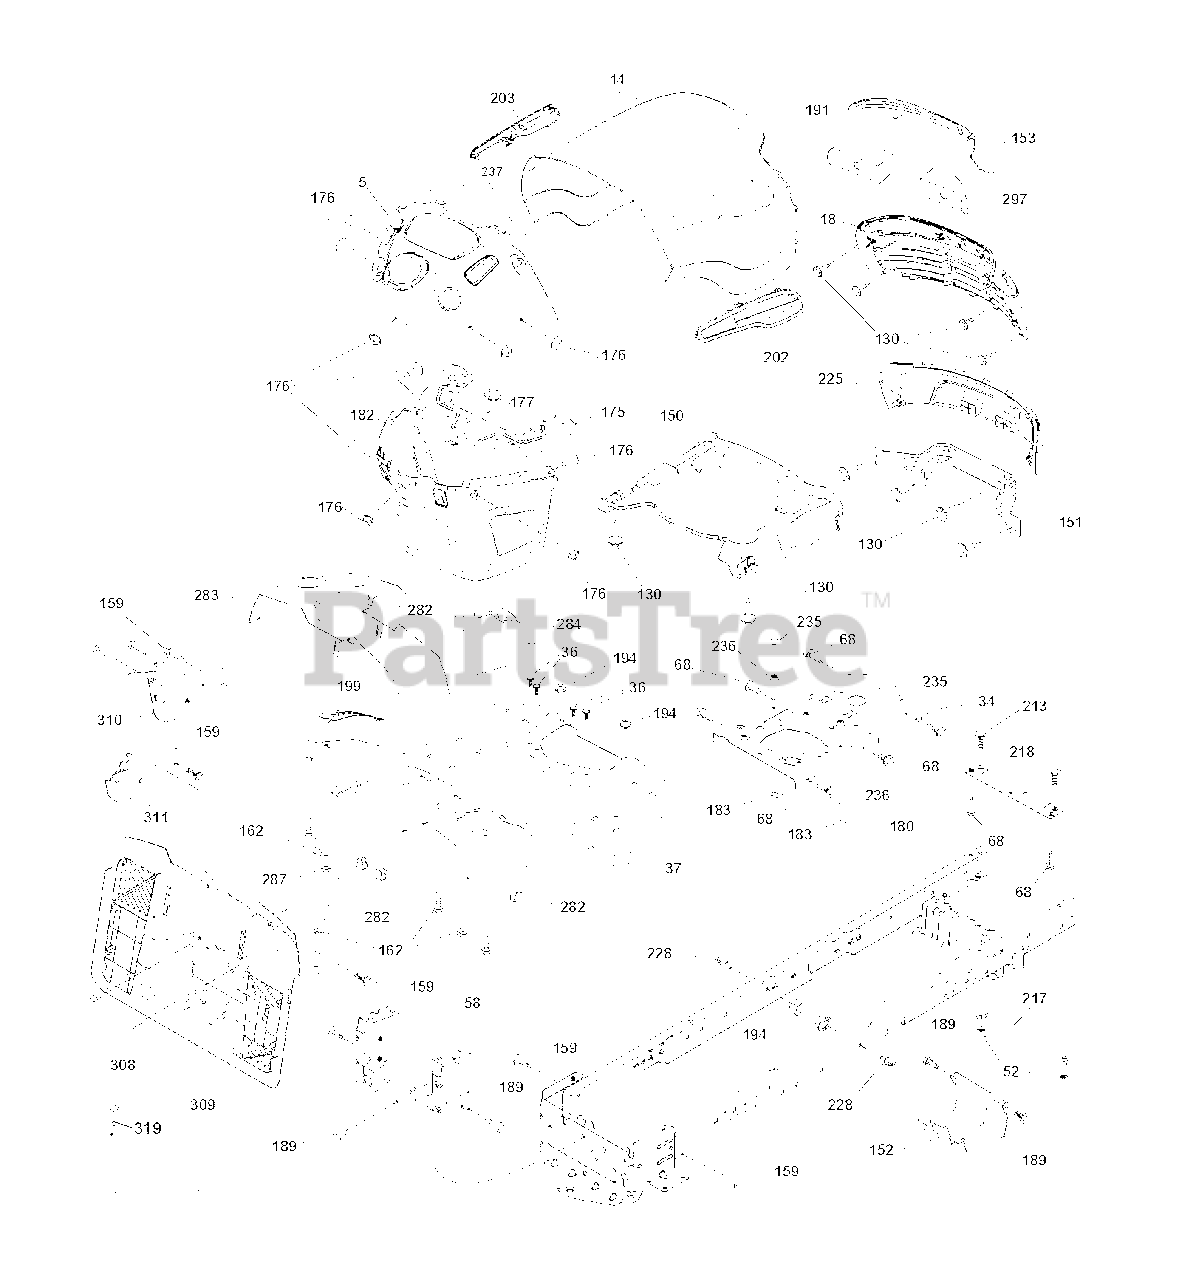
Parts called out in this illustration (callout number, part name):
34	PLATE.ENGINE.WELDED.CHASSIS
36	SCREW 5/16"
52	LOCKNUT
58	DRAWBAR UPPER 2PC SMALL FENDER
130	SCREW.#10 X 0.750.BOS THREAD
151	BRACKET.PIVOT.ALPHA.LT
152	SHIELD BROWNING
159	SCREW, 3/8-16X3/4
162	SCREW.HI-LO.CONSOLE
175	CROSSMEMBER
176	SCREW.#10-24X5/8.RN.QU
177	BUSHING STEERING
182	DASH.LWER.PREDATOR/HUSQ.LT
183	BOLT.5/16-18X1-1/4 FULL.THREAD
189	SCREW
191	REFLECTOR.INSERT.PRED.LH.LT
194	NUT LOCK HEX FLANGE 5/16-18
213	BOLT
217	ROD.PIVOT.HOOD
218	X-PIECE.HOOD.STOP.NON/
228	STUD.FASTNER.W/ANTI-ROTATE
235	SPACER FENDER
236	NUT.CENTERLOCK.5/16-
237	PLUG.MOUNT.CARGO.BLK
282	CLIP.RETAINER.CONSOLE.LT.HUSQ
297	INSERT.REFLECT.PREDATOR.LT.RH
308	BOLT, 5/16-18 X 1 3/4
